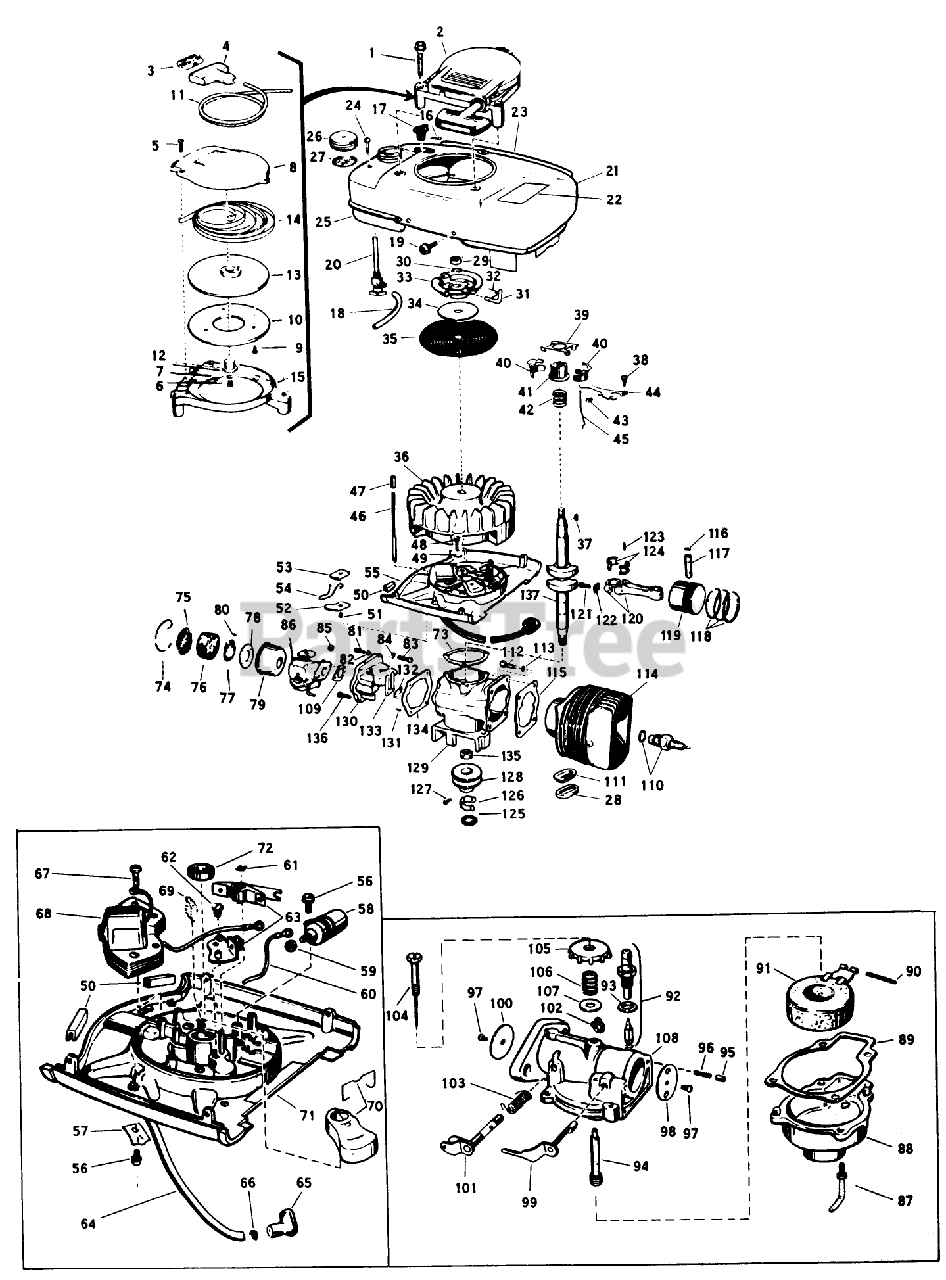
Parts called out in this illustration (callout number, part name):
10	Plate-Pulley
14	RECOIL SPRING
16	Cotter Pin-Choke Knob
17	KNOB, CHOKE BAR
19	SCREW S
20	VALVE&SCREEN SM
31	PIN - STARTER
41	COLLAR S
43	WEAR BLOCK S
44	GOVERNER LEVER AY
45	GOVERNOR ROD S
51	Screw Shut-off Switch
63	BREAKER AY. S
65	Cover-Rubber
73	GASKET S
76	ELEMENT
78	BACK-UP PLATE
81	SCREW S
85	STOP NUT
97	Screw-Choke Disc
99	CHOKE SHAFT&LVR AY
103	SPRING
104	NEEDLE AY. S
106	Spring-Ndl. Adj.
109	GASKET S
110	Spark Plug
115	GASKET S
116	RING-RETAINING
124	LINER ASM
132	PLATE-BACKUP, REED
136	SCREW S
